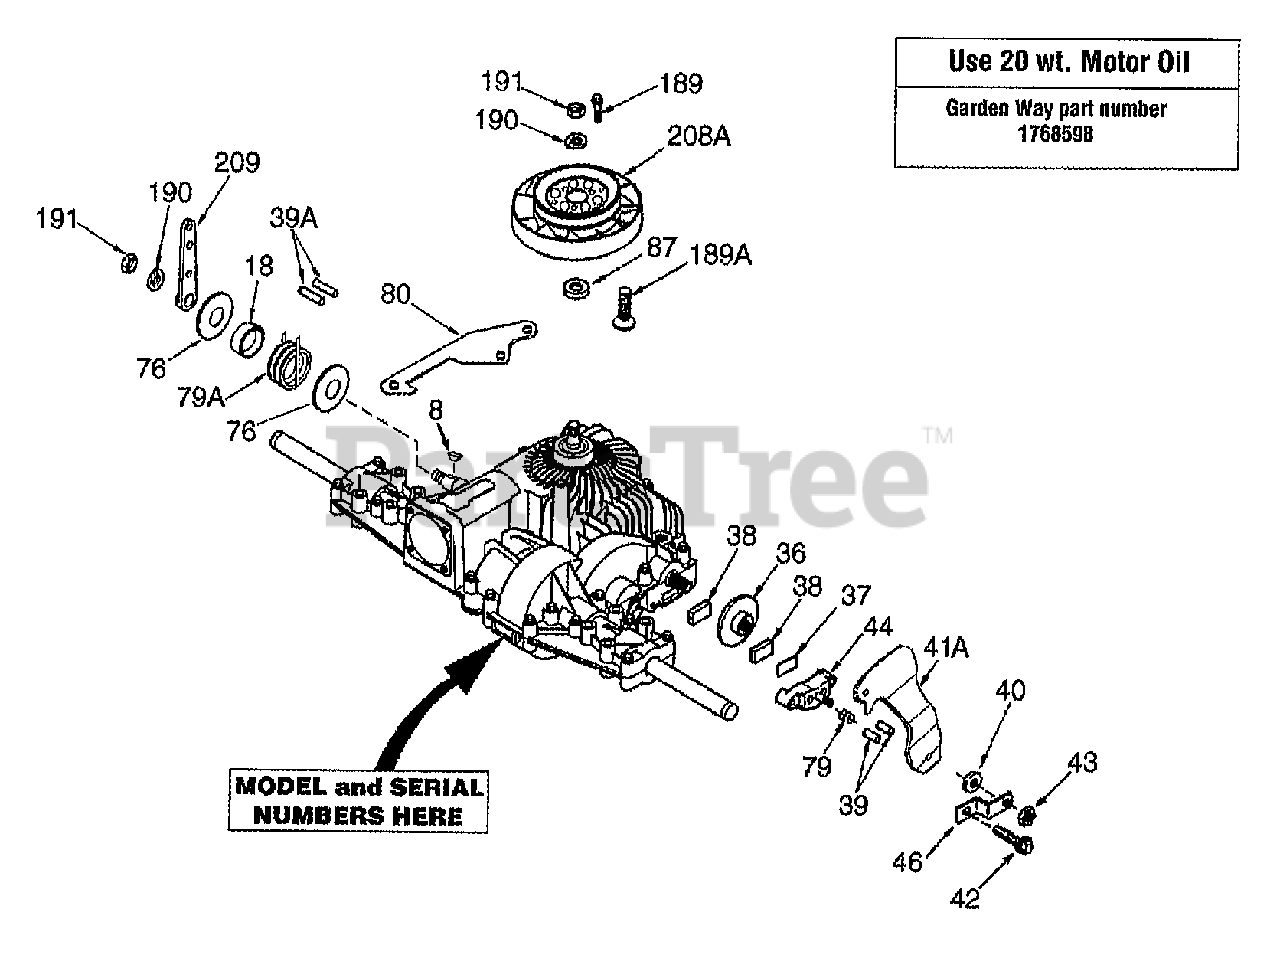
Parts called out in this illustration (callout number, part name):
8	WOODRUFF KEY
36	BRAKE DISK
37	BRAKE PAD PLATE
38	BRAKE PAD
39	DOWEL PIN
39A	DOWEL PIN
41A	BRAKE LEVER
80	CONTROL STOP
87	OIL SEAL
208A	FAN & COUPLING
209	CONTROL LEVER
